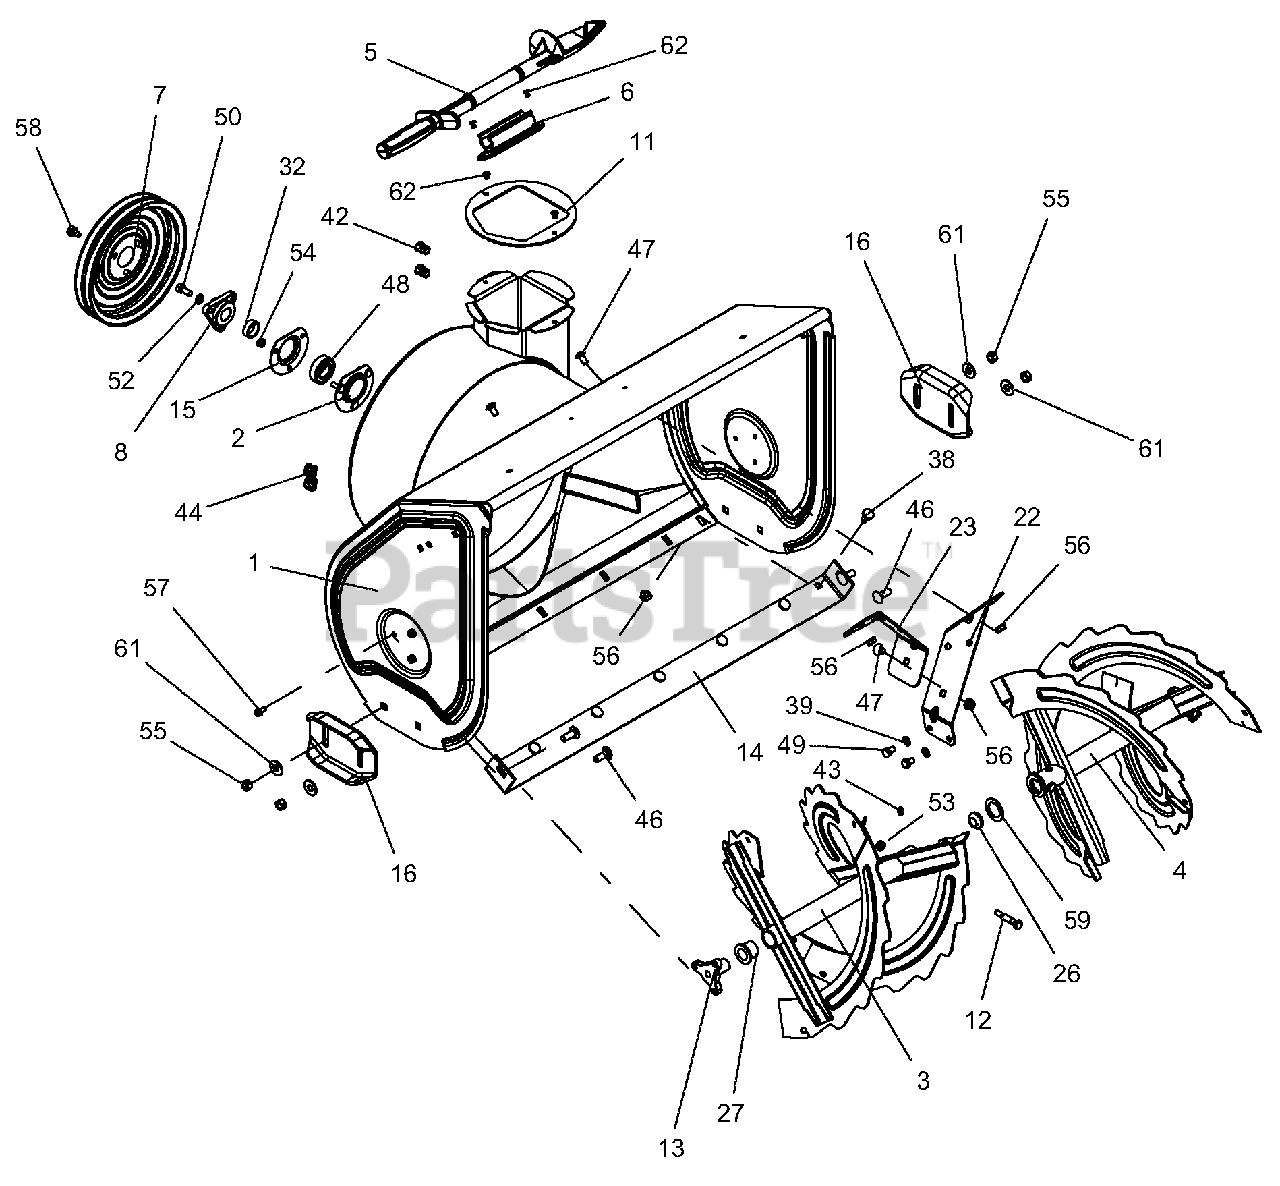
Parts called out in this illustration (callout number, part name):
1	BLOWER HOUSING W/DECAL 30"
2	BEARING FLANGE
3	RAKE, RH W/ZERK - 30"
4	RAKE, LH W/ZERK - 30"
5	DEVICE, SNOW CLEAN OUT
6	MOUNT, SNOW CLEAN OUT
7	PULLEY, SPIN FORM DUAL GROOVE
8	PULLEY HUB, D-BORE .87 DELUXE
11	BAFFLE, DISCHARGE NECK
12	SHEAR BOLT SERVICE ASSEMBLY
13	SUPPORT, RAKE BUSHING
14	BLADE, SCRAPER-30"
15	BEARING FLANGE
16	SKID SHOE, REVERSIBLE - ORANGE
22	BRACKET, GEARCASE SUPPORT - LH
23	BRACKET, GEARCASE SUPPORT - RH
26	PLUG, RAKE TUBE
27	BSHG-FLG, NY.778 ID X 1.018 OD
32	BSHG-SPCR .895IDX1.065ODX.353
38	BOLT, MODIFIED HEAD CARRIAGE
39	@WSHR-LK-EXT.326X.599X.031YWZC
42	NUT, THREADED INSERT .38-16
43	ZERK,FITTING .25X.125 DRIVE IN
44	SCR-TAP.31-18X.50 HWH TR YWZ
46	@BLT-RDHDSHSQNK.38-16X1.0 G5YZ
47	BLT-RDHDSQSHNK.31-18X.62 YZ-LK
48	BRG-BALL .876 X 1.750 X .50
49	@BLT-HEX .31-18X.50 GR5 YWZC
50	BLT-HEX .31-24X.75 YWZC GR5
52	WSHR-LK .312X.097 HVY YWZC
53	@NUT-LK-CTR .31-18 YWZC
54	@NUT-LK-CTR .25-20 YWZC
55	@NUT-LK-CTR .38-16 YWZC
56	@NUT-LK-TOP-FLG .31-18 YWZC
57	SCR-TAP .25-20X.50 HWH TR YWZ
58	@SCR-TAP .31-18X.50 HWH TR YWZ
59	WSHR-FL-STL 1.010X1.505X.062YZ
61	@WSHR-FL-STL.438X1.00X.083 YWZ
62	RVT-POP .187 YZ
